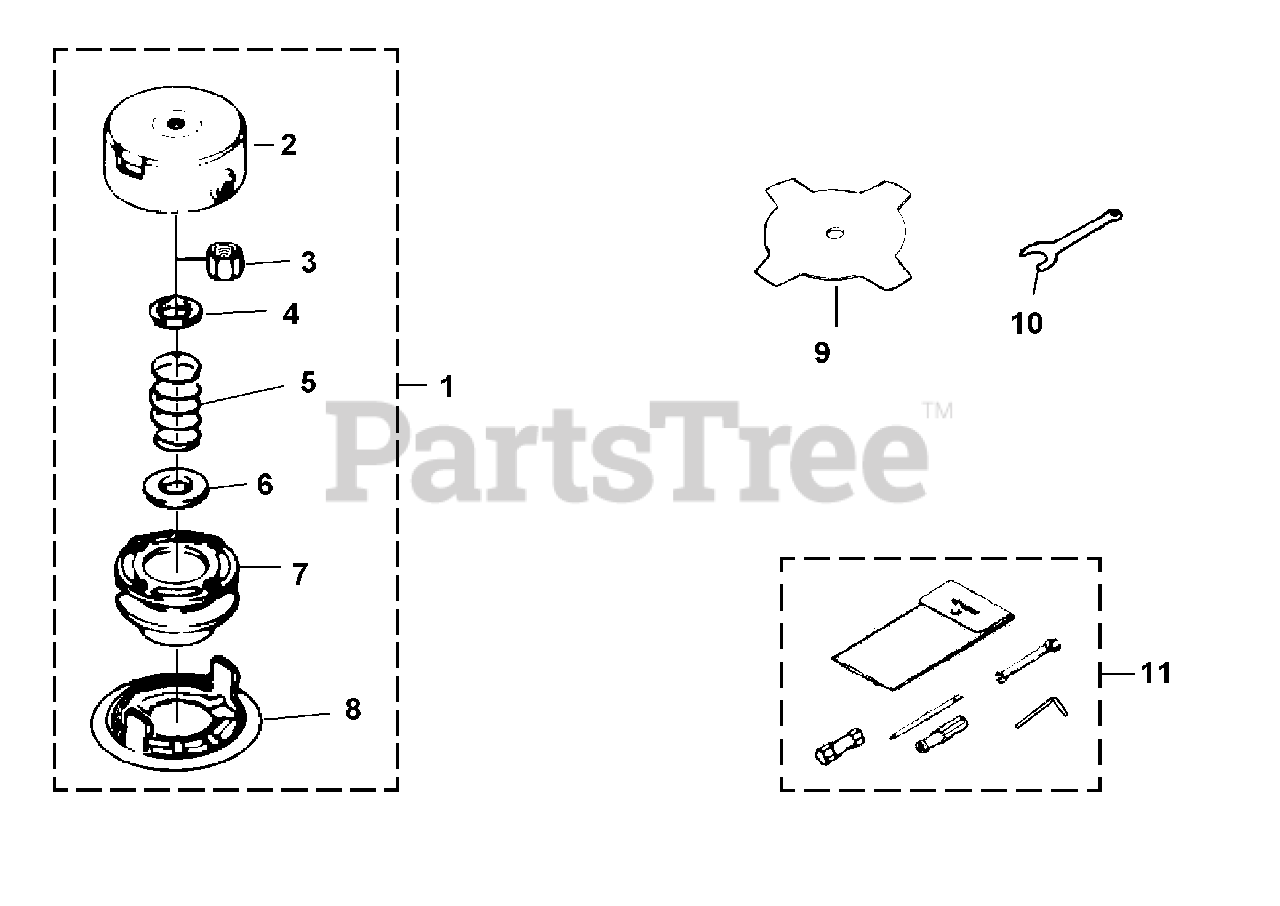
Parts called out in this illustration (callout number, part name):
1	6" TFC Stringhead Assembly
2	Stringhead Body
3	Arbor Nut
4	Spring Plate
6	Spring Plate
8	6" Cap
9	Quad Blade
10	Spanner Wrench
